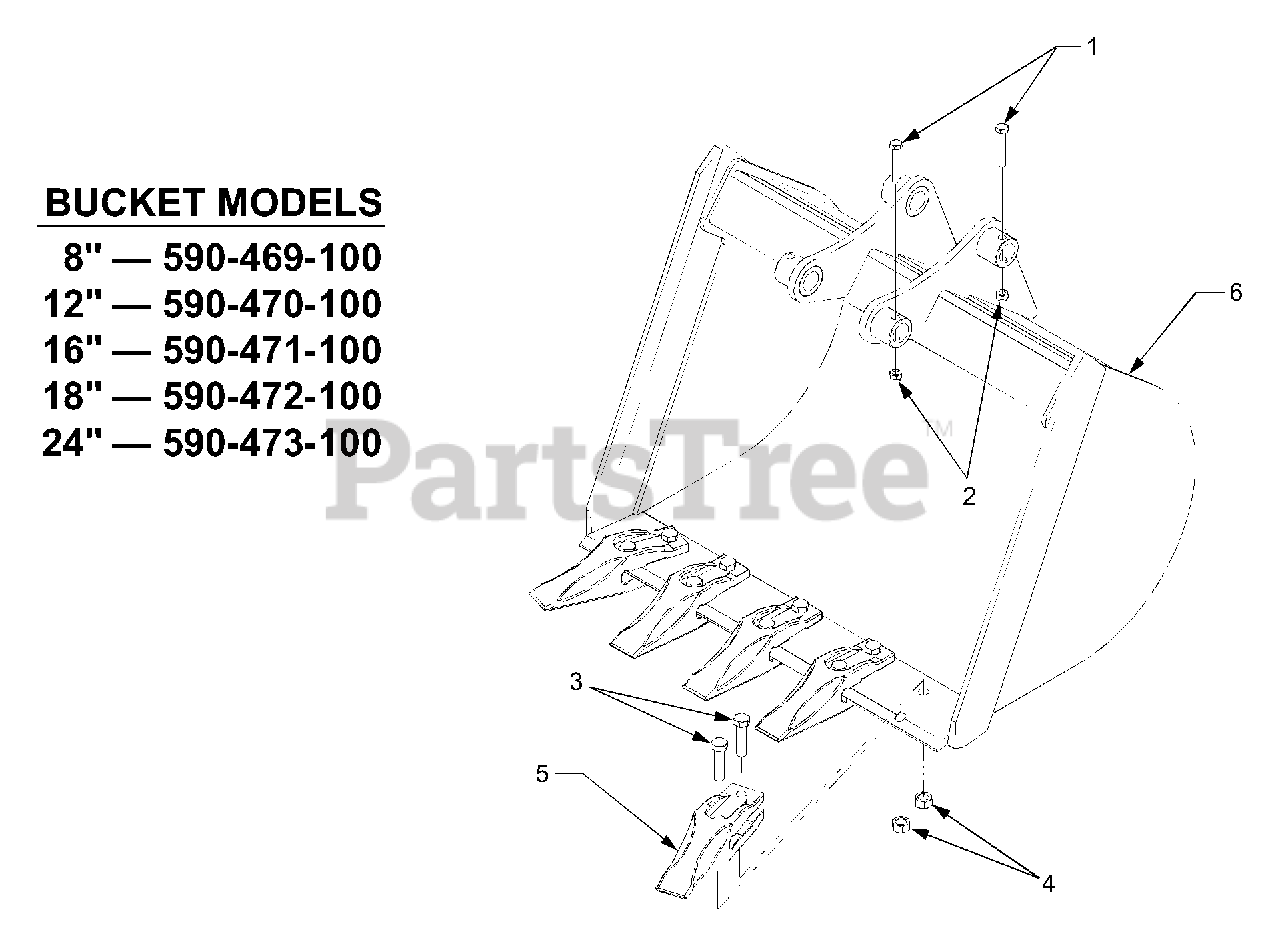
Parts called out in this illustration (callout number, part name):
1	Screw, Hex Cap, M8-1.25 x 50 Hardened
2	Nut, Hex Nylon Lock, M8-1.25
3	Screw,Hex Cap, M12-1.75 x 45 GR8.8 8" and 12" Bucket
4	Nut, Hex, M12-1.75 8" and 12" Bucket
5	Tine, Backhoe 8" and 12" Bucket
6	8" Bucket Assembly
